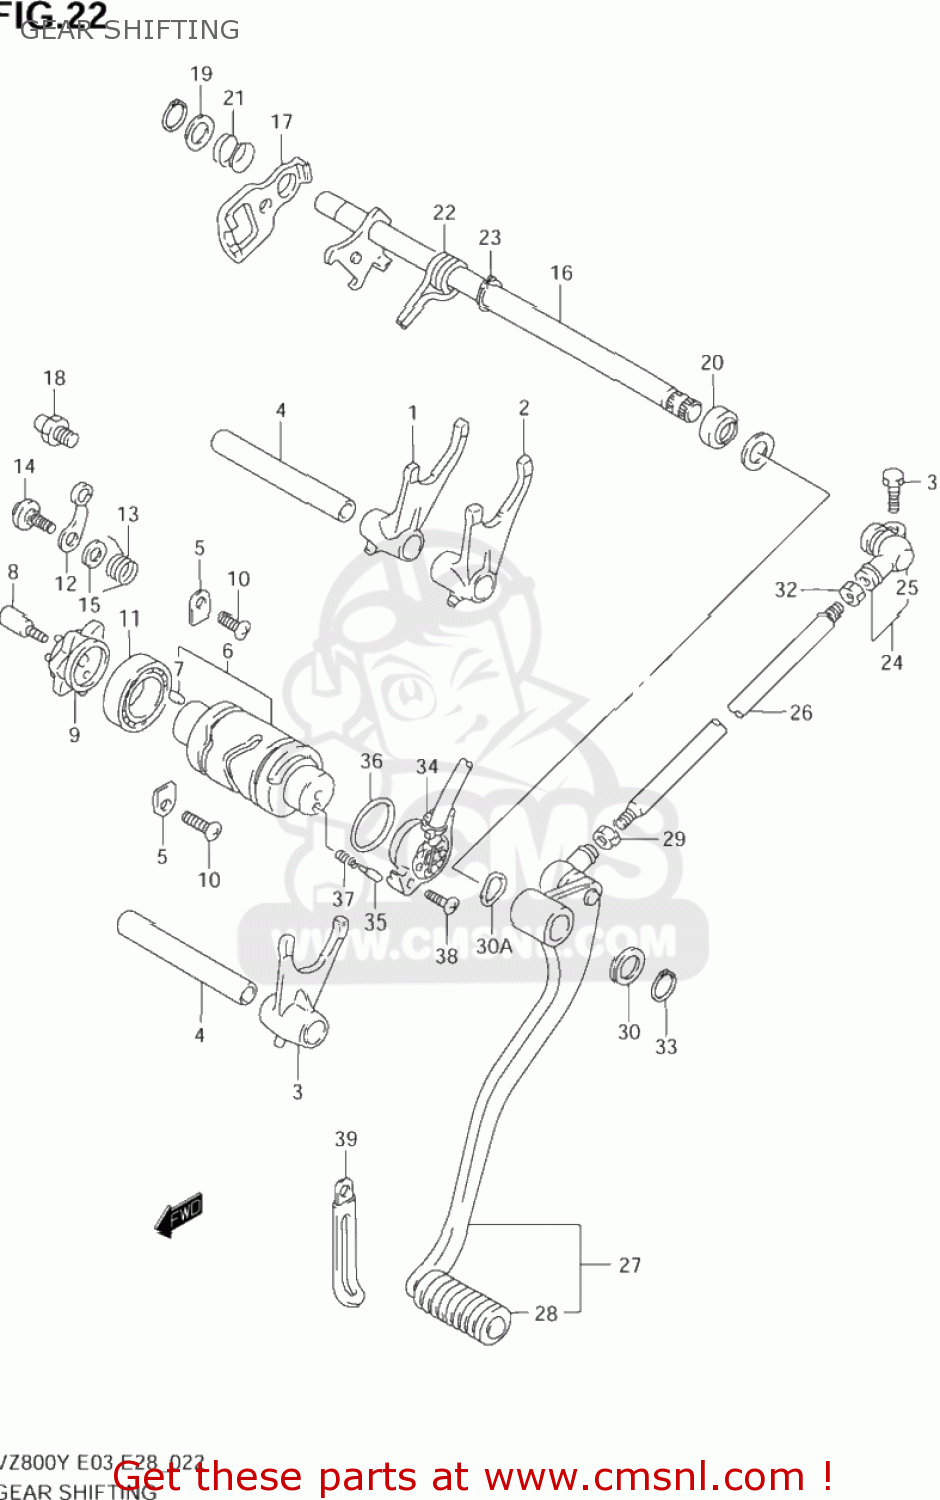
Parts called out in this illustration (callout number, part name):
1	FORK,GEAR SHIFT NO.1
2	FORK,GEAR SHIFT NO.2
3	FORK,GEAR SHIFT NO.3
4	SHAFT,GEAR SHIFT FORK NO.1
5	RETAINER
6	CAM,GEAR SHIFT
7	PIN
8	PIN,SHIFT CAM DRIVEN GEAR
9	PLATE,GEAR SHIFT CAM
10	SCREW
11	BEARING
12	STOPPER,GEAR SHIFT CAM
13	SPRING,SHIFT CAM STOPPER
14	BOLT(6X14.3)
15	WASHER
16	SHAFT,GEAR SHIFT
17	PLATE,GEAR SHIFT CAM D
18	STOPPER,GEAR SHIFT CAM
19	SHIM(14X22X1)
20	SEAL,OIL(14X22X6)
21	SPRING
22	SPRING
23	CIRCLIP
24	ARM,GEAR SHIFT SHAFT
25	COVER,DUST
26	ROD,GEAR SHIFT LINK
27	LEVER ASSY,GEAR SHIFT
28	RUBBER,GEAR SHIFT PEDAL
29	NUT
30	WASHER(12.5X20X1)
30A	WASHER
31	SCREW
32	NUT
33	CIRCLIP,12 MM
34	BASE ASSY,NEUTRAL SW TERMINAL
35	PIN(5X15.5)
36	O RING(D:2.4,ID:25.7)
37	SPRING
38	SCREW
39	CLAMP L:62
